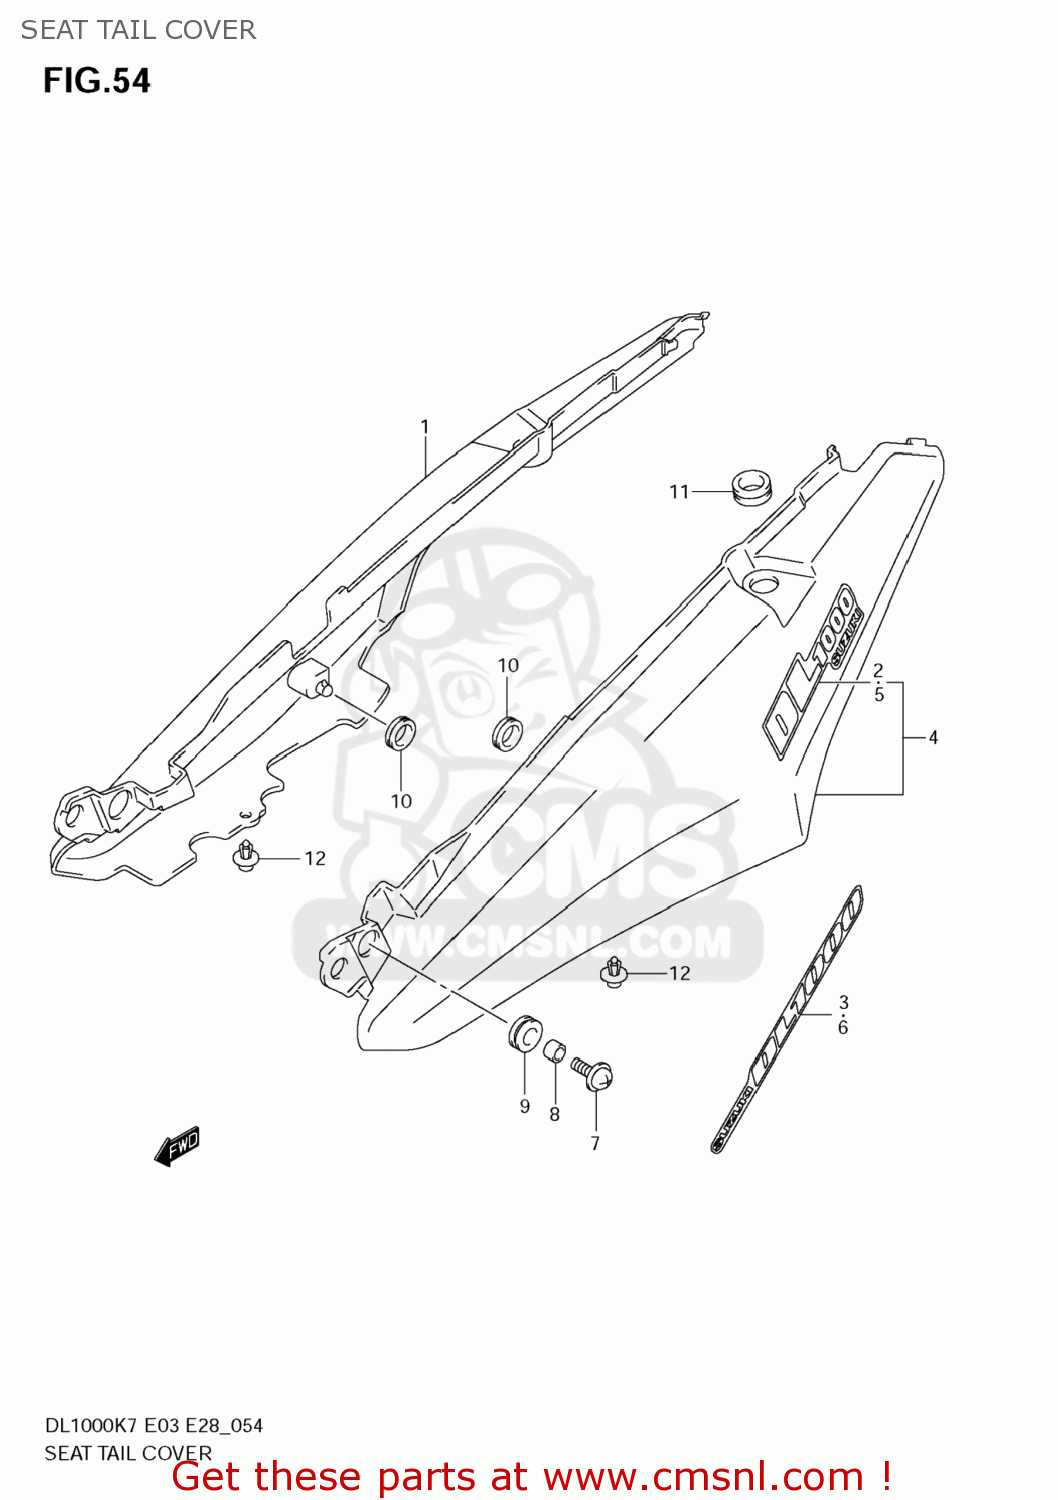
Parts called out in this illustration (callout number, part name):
1	COVER,SEAT TAIL,R(GRAY)
2	EMBLEM,SEAT TAIL COVER
3	EMBLEM,SEAT TAIL COVER
4	COVER,SEAT TAIL,L(GRAY)
5	EMBLEM,SEAT TAIL COVER
6	EMBLEM,SEAT TAIL COVER
7	SCREW(6X20)
8	SPACER(6.5X12X9)
9	CUSHION
10	CUSHION
11	CUSHION
12	CLIP(BLACK)
